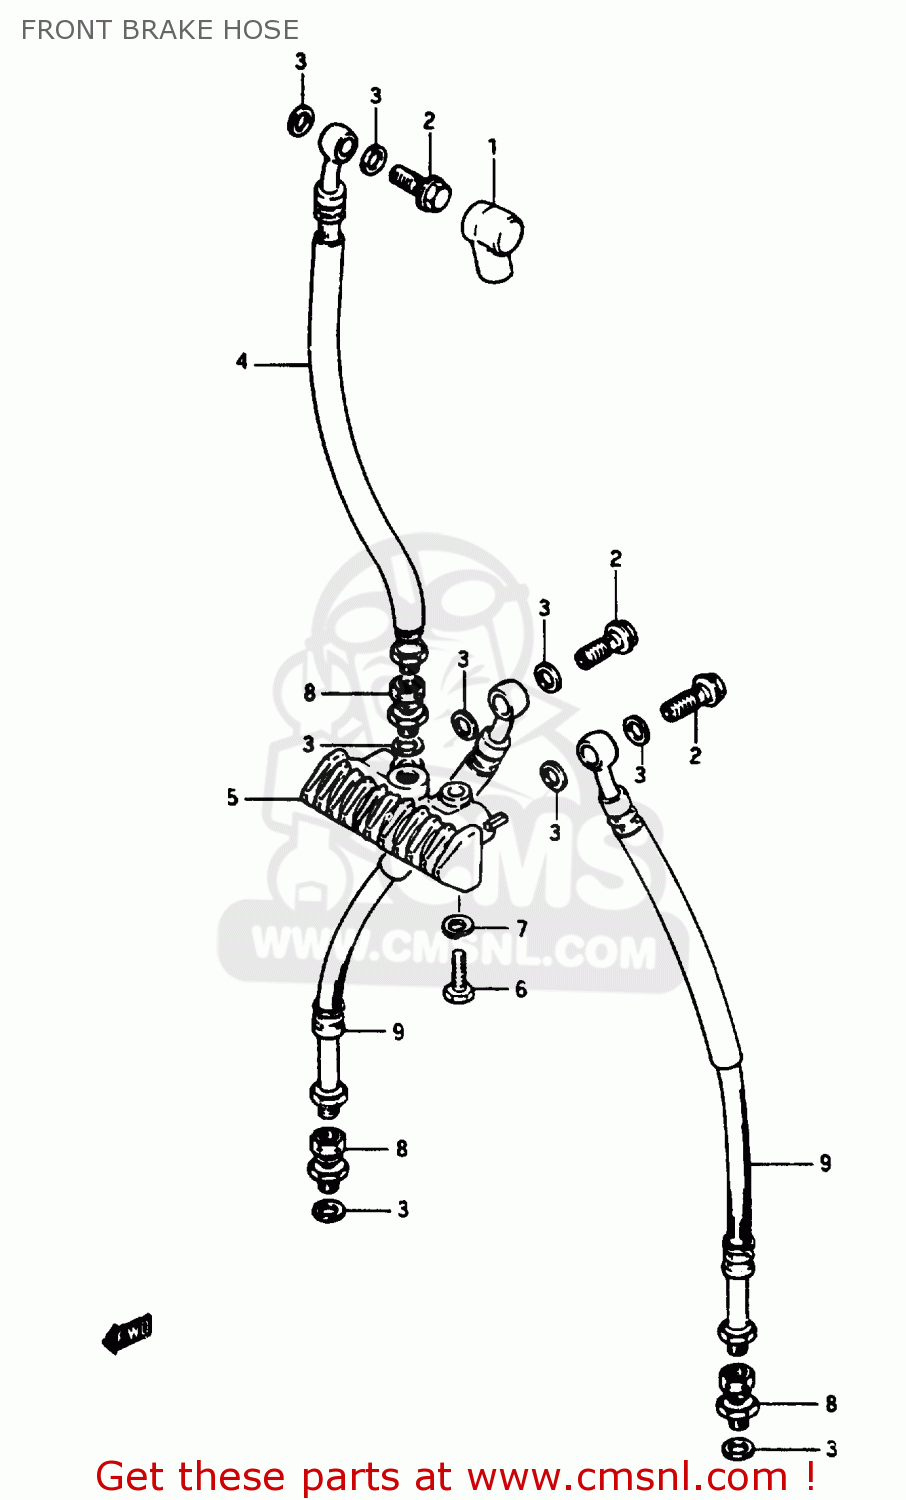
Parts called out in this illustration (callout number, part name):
1	BOOT,MASTER CYLINDER
2	BOLT UNION
3	WASHER(10X15X1.5)
4	HOSE,FRONT BRAKE
5	JOINT,BRAKE HOSE
6	BOLT
7	WASHER,LOCK
8	ADAPTER,BRAKE HOSE
9	HOSE,FRONT BRAKE NO.2
